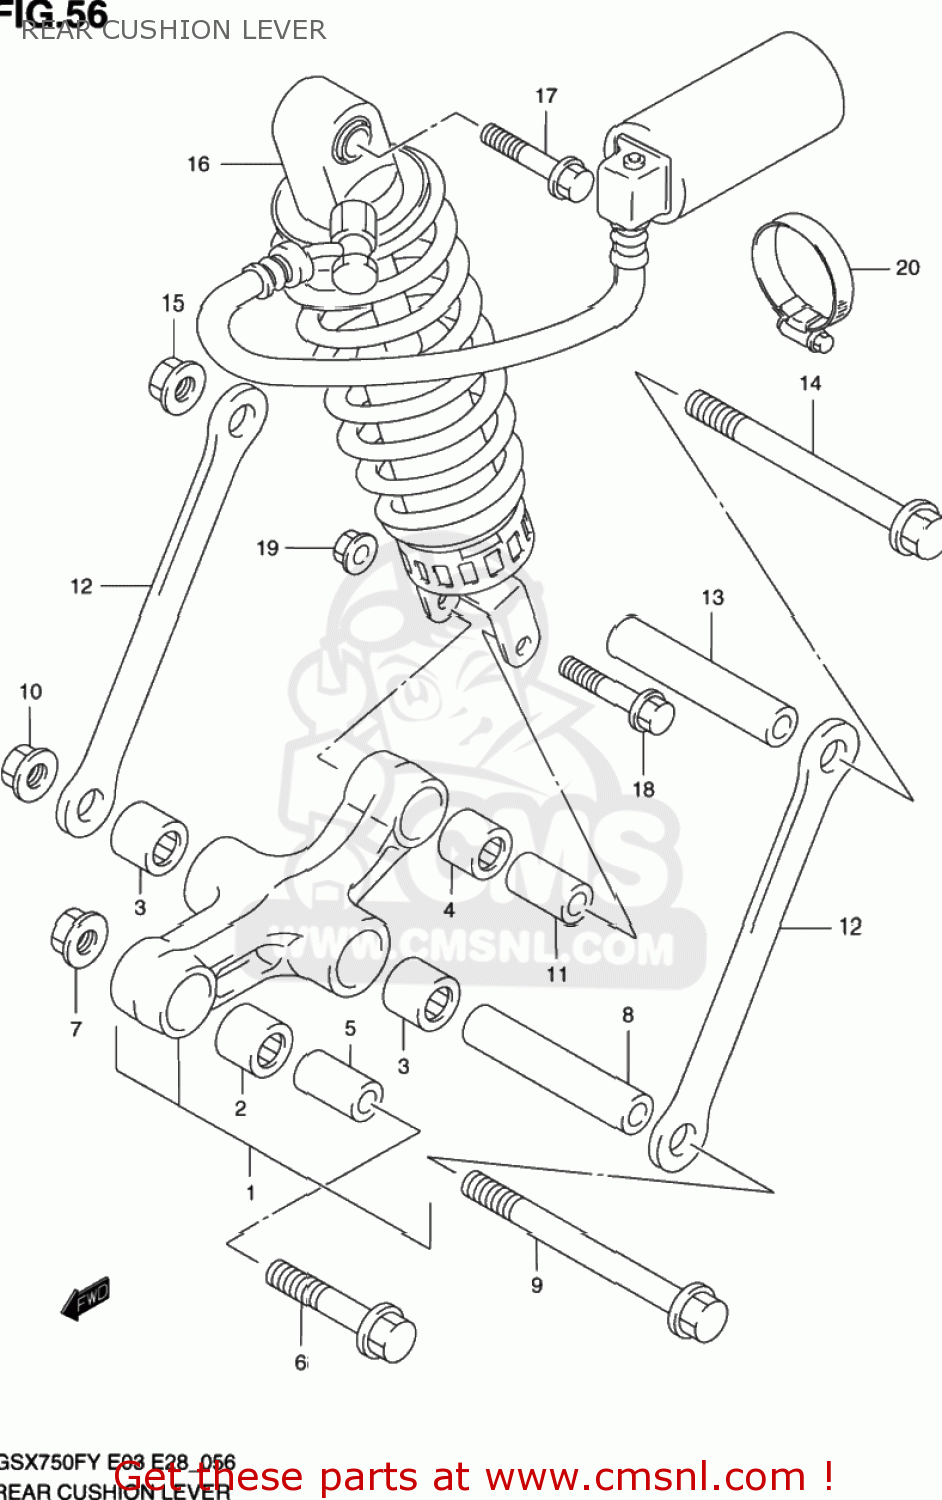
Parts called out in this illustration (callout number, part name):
1	LEVER SET,RR CUSHION
2	BEARING(20X27X30)
3	BEARING(20X27X23.5)
4	BEARING(17X24X26)
5	SPACER(14X20X34)
6	BOLT(14X62)
7	NUT
8	SPACER,RR CUSHION ROD
9	SHAFT,RR CUSHION ROD
10	NUT
11	SPACER,RR CUSHION LEVER
12	ROD,RR CUSHION
13	SPACER,RR CUSHION ROD
14	SHAFT,RR CUSHION ROD
15	NUT
16	ABSORBER ASSY,RR SHOCK
17	BOLT(10X52)
18	BOLT(10X44)
19	NUT
20	CLAMP
